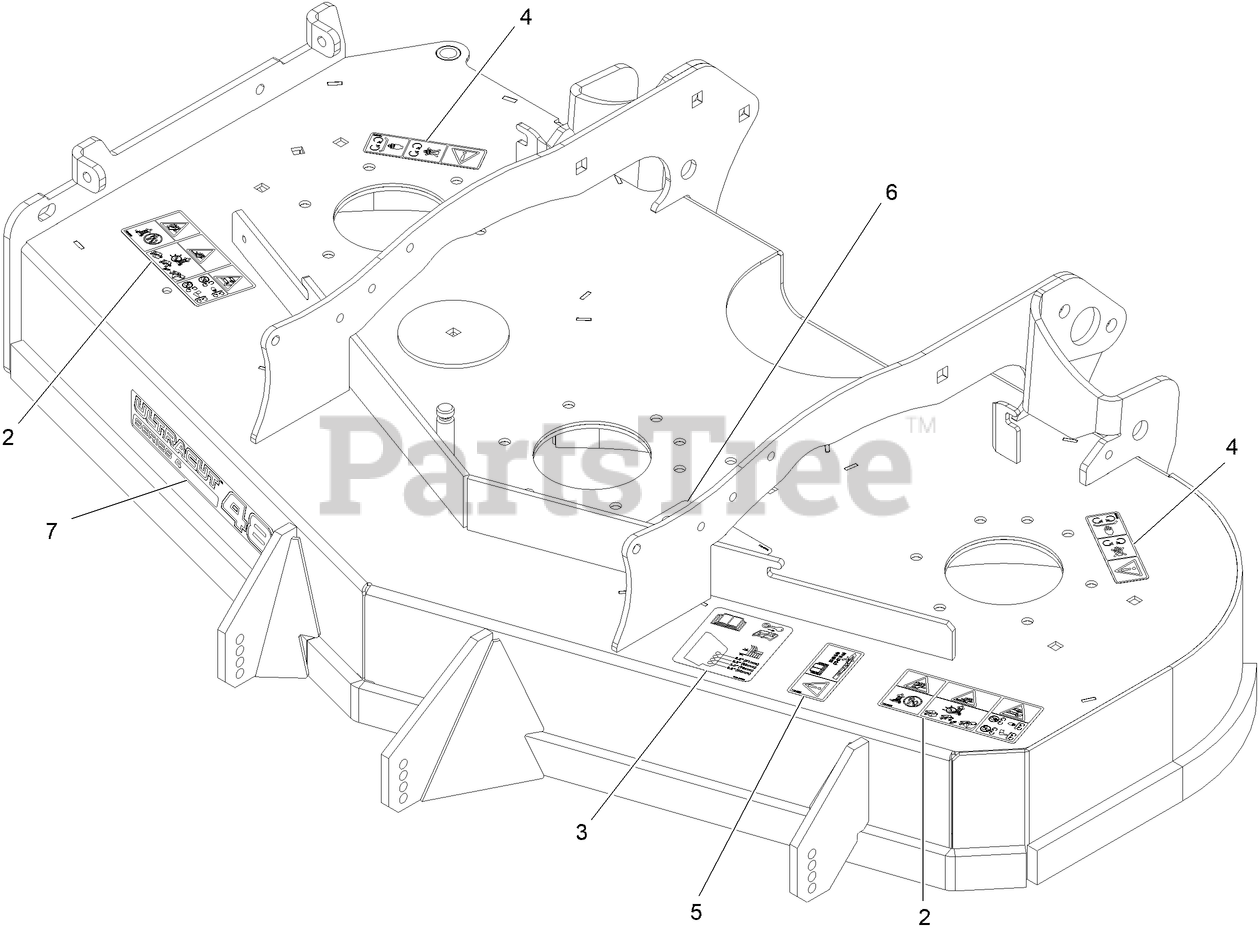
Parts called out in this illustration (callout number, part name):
2	DECAL-WARNING THROWN OBJ
3	DECAL-ROLLER, ANTI-SCALP
4	DECAL-COVER, MISSING
5	DECAL-TORQUE, BOLT
6	DECAL-BELT ROUTING
7	DECAL, 484
